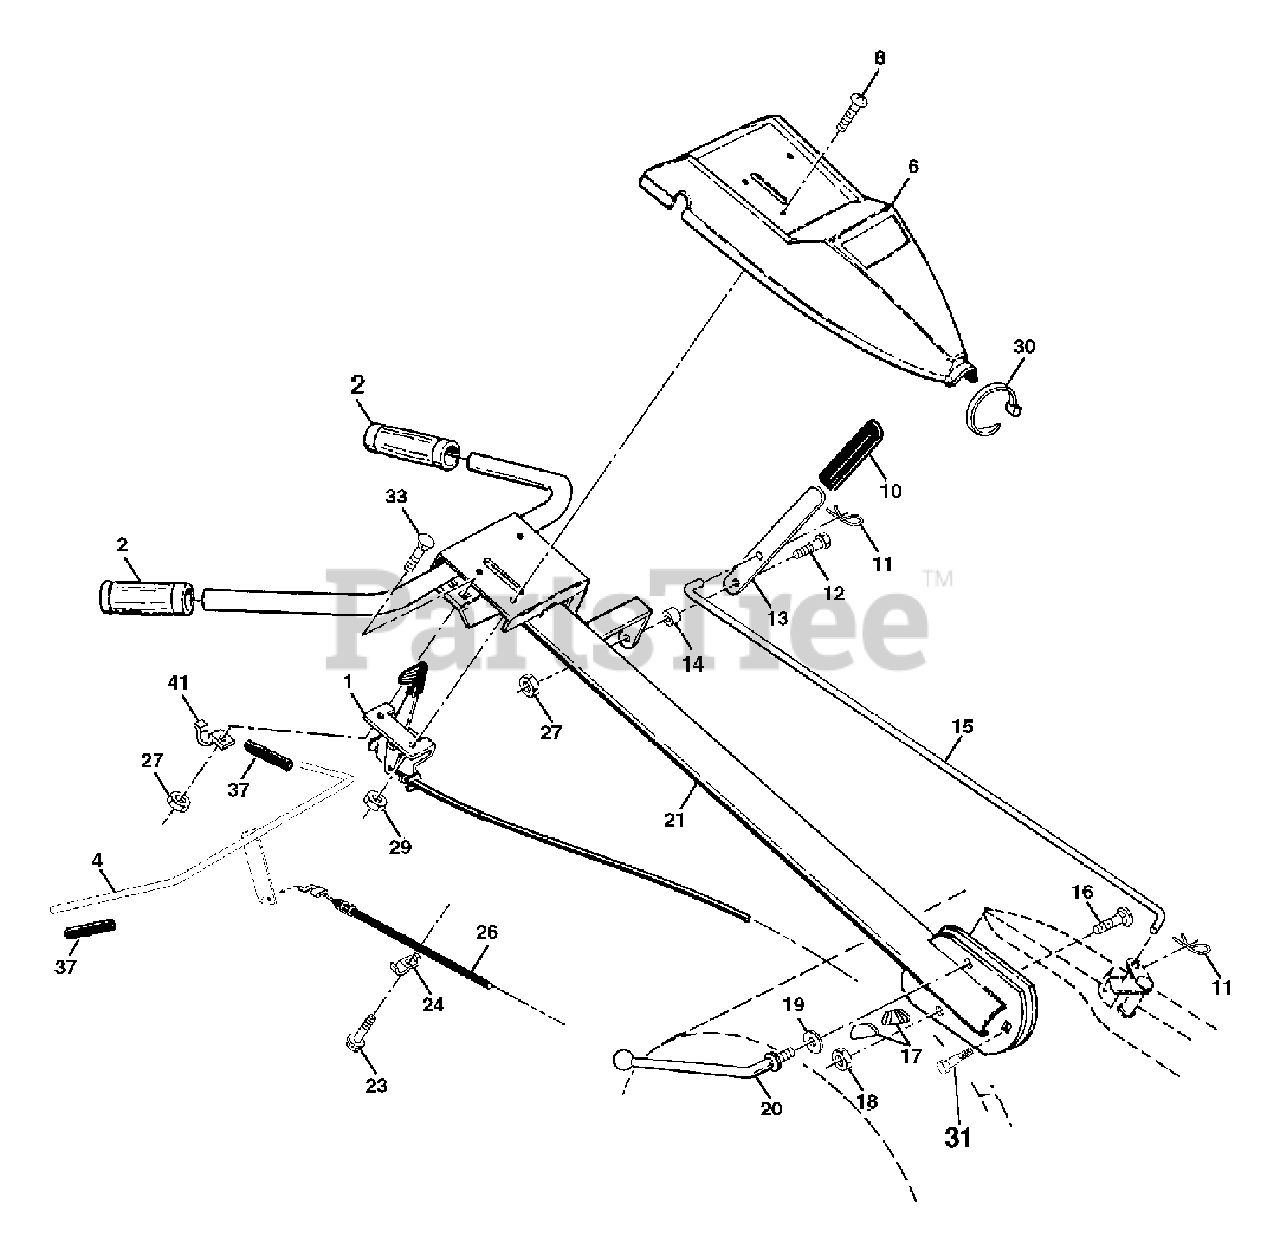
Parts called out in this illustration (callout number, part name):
1	Control, Throttle
2	Grip, Handle
4	Bar Assembly, Control
6	Panel, Control
8	Screw, Phd. #10-24
10	Grip, Handle
11	Clip, Hairpin
12	Bolt, Shoulder
13	Handle, Shift
14	Grommet, Rubber
15	Rod, Shift
16	Bolt, Carriage 3/8-16 x 1 Gr. 5
17	Lock, Handle
18	Nut, Crownlock 3/8-16 Unc
19	Washer 13/32 x 1 x 11 Ga.
20	Lever, Lock, Handle
21	Handle
23	Screw, Hex Washer Hd. Slotted #10-24 x 1/2
24	Clip
26	Cable, Clutch
27	Nut Hex Flange 1/4-20 Unc
29	Nut, Keps #10-24 UNC
30	Tie, Cable
31	Bolt, Pivot
33	Bolt, Carriage 1/4-20 UNC x 1/2
37	Grip, Bar, Control
41	Clamp,Bar, Control
